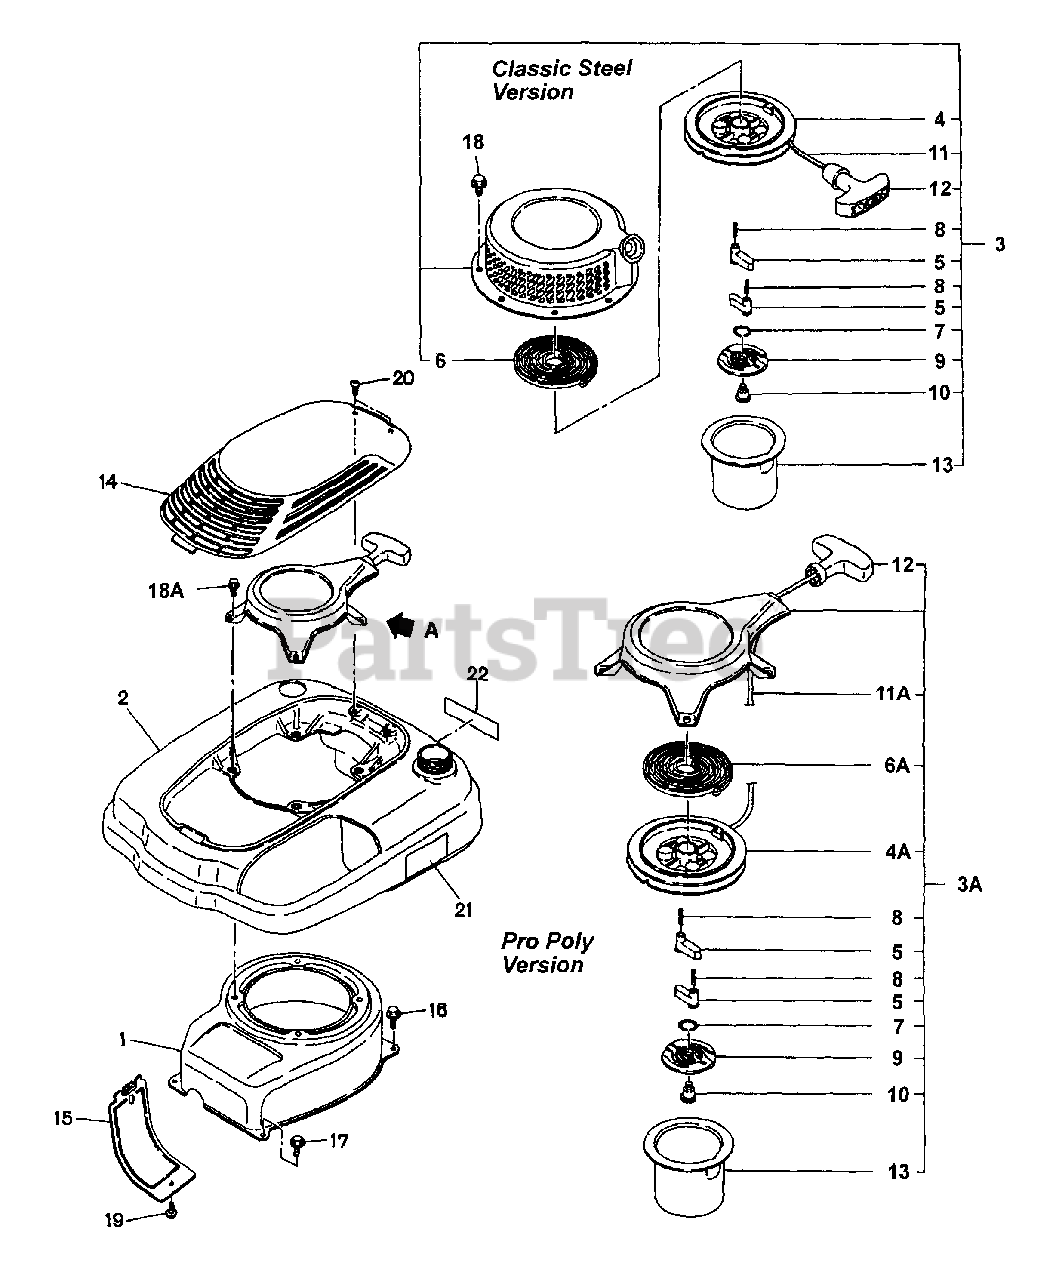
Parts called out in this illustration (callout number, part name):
1	BLOWER HOUSING, compl. (Pro Poly)
1	BLOWER HOUSING, compl., green (Classic Steel)
1	BLOWER HOUSING, compl., black (Classic Steel)
2	ENGINE SHROUD/TANK (Pro Poly)
3	RECOIL STARTER ASS'Y
3A	RECOIL STARTER ASS'Y
4	REEL (Classic Steel)
4A	REEL (Pro Poly)
6	SPIRAL SPRING
6A	SPIRAL SPRING
7	FRICTION SPRING
8	RETURN SPRING
9	RATCHET GUIDE
11	STARTER ROPE, std
11A	STARTER ROPE, extended rope start(ERS)
12	STARTER KNOB
13	STARTER CUP
15	CYLINDER BAFFLE
16	FLANGE BOLT
17	FLANGE BOLT
18	FLANGE BOLT
18A	FLANGE BOLT
19	FLANGE BOLT
20	TAPPING SCREW
21	LABEL, warning
22	LABEL, emission control
